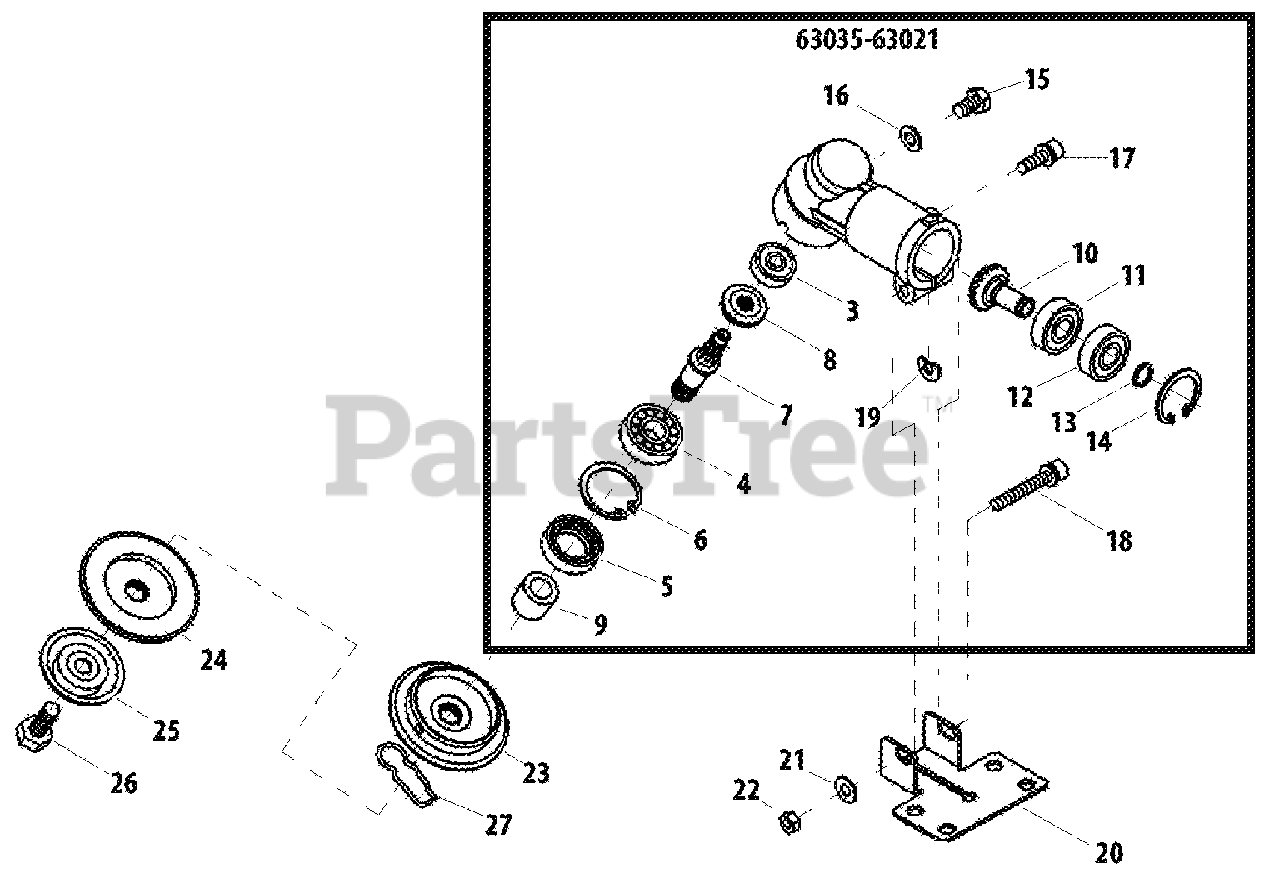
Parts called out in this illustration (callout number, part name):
3	BEARING, BALL
4	BEARING, BALL 6201
5	SEAL, OIL
6	RING, SNAP Ø32
7	SHAFT, GEAR
8	GEAR, BEVEL
9	SPACER
10	GEAR, PINION
11	BEARING, BALL 6901
12	BEARING, BALL 6901ZZ
13	RING, SNAP Ø12
14	RING, SNAP Ø24
15	BOLT M6×10
16	WASHER
17	BOLT M5×16
18	BOLT M6×40
19	D-WASHER
20	PLATE, SHIELD MOUNTING
21	WASHER 6.5×13×1
22	NUT, HEX M6
23	PLATE, ADAPTOR - UPPER
24	PLATE, ADAPTER - UPPER
25	GUARD, BOLT
26	BOLT 8
27	CLIP, BLADE
6303563021	GEAR CASE ASSY
